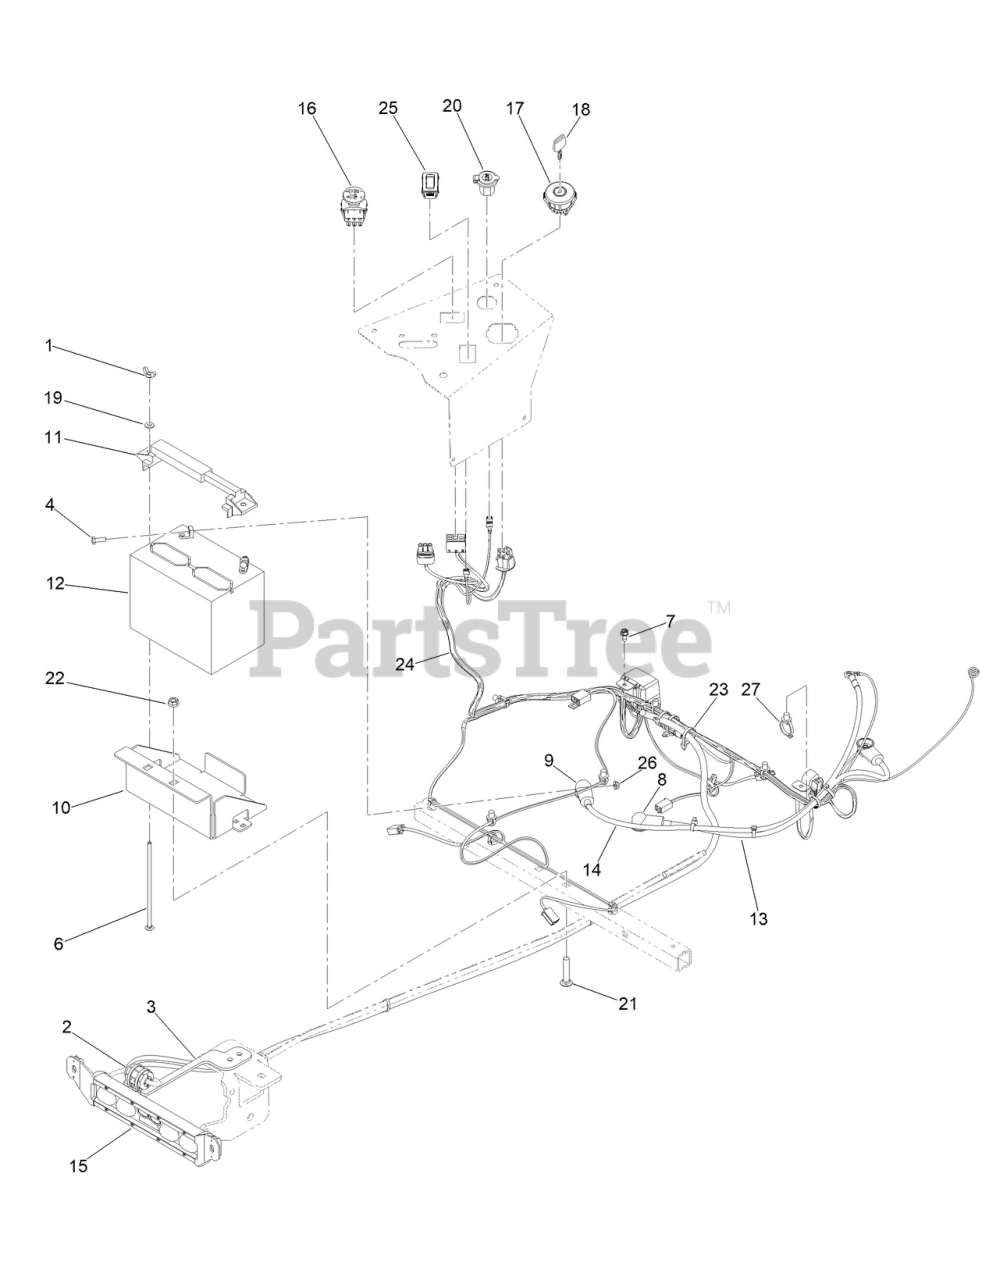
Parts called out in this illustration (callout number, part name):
1	NUT-WING
2	FAIR-RITE ROUND CABLE SNAP-IT SIZE B
3	FAIR-RITE BRACKET PAINTED
4	SCREW-HH
6	1/4-20 X 7 CARRIAGE BOLT ZINC
7	SCREW-HWH
8	3.15 LGTH STRAIGHT INSUL TERM COVER RED
9	STRAIGHT INSULATING TERMINAL COVER
10	MWR BATTERY BOX
11	BATTERY HOLD DOWN
12	MWR START BATTERY 350CCA
13	MWR POSITIVE BATTERY CABLE 25IN
14	MWR NEGATIVE CABLE 28
15	FULL BEAM WITH LIGHTED HELMET LIGHT BAR
16	PTO SWITCH
17	IGNITION SWITCH
18	2023 MWR KEY
19	WASHER-FLAT
20	12 VOLT AUXILLIARY PLUG
21	SCREW-CARR
22	3/8-16 HEX FLANGE NUT W/SERR ZINC YELLOW
23	TIE-CABLE
24	HARNESS-WIRE
25	HOUR METER
26	NUT-HF
27	CLIP-TIE
